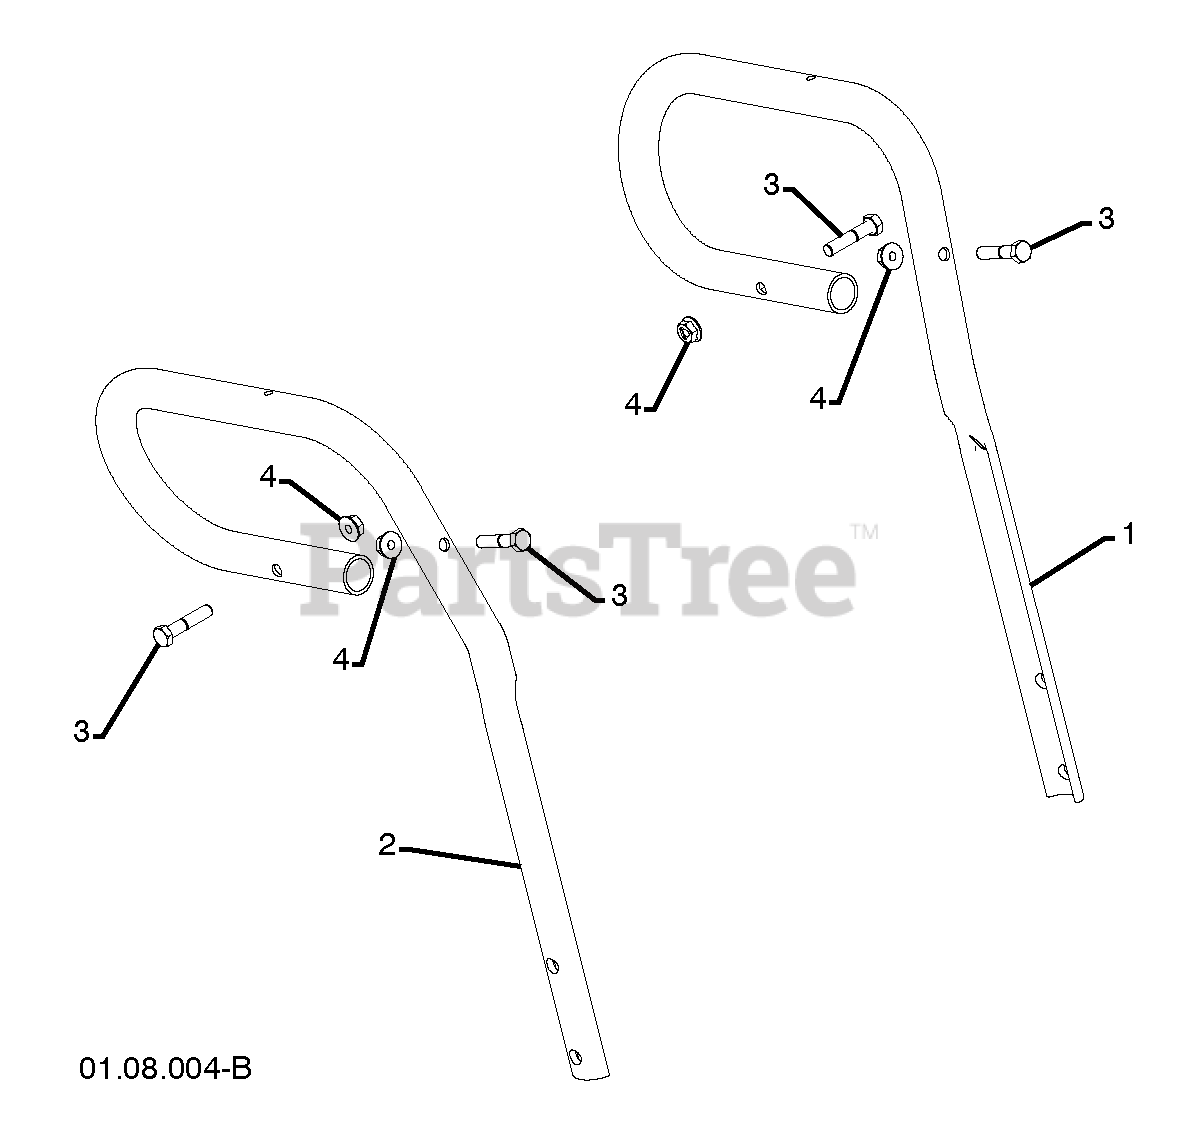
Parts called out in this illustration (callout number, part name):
1	LOOP HANDLE LH
2	LOOP HANDLE RH
3	SCREW 5/16-18 X 1.50
4	NUT 5/16-18
